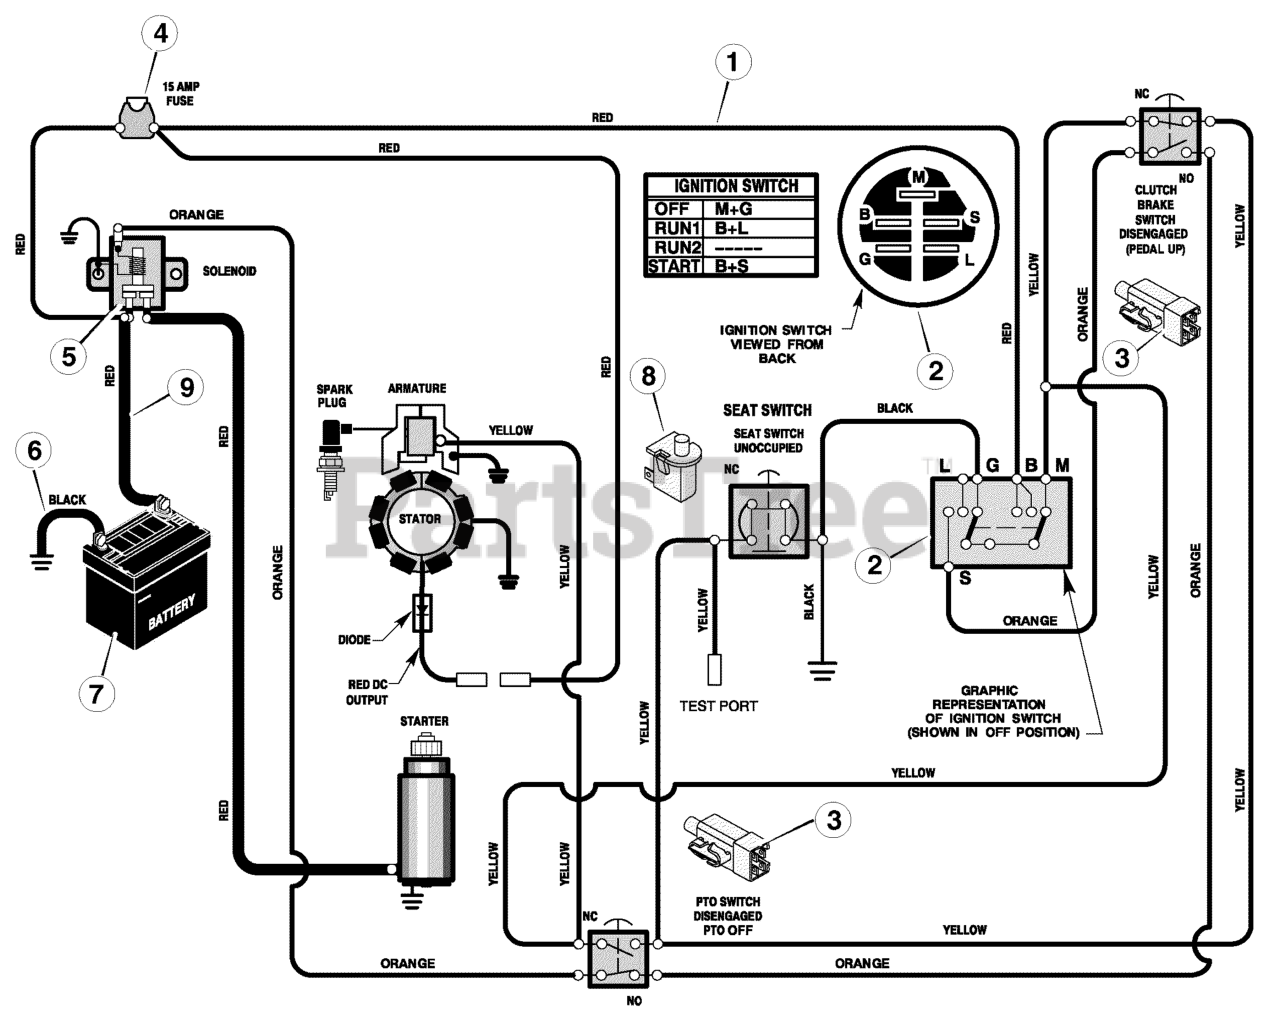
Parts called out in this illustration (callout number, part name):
1	Harness, Chassis Wire
2	Switch, Ignition
2	Key, Ignition
3	Switch, Limit
4	Fuse
4	Holder, Fuse
5	Solenoid
5	Screw, Mounting
5	Locknut
6	Cable, Battery Ground
6	Screw, Ground Cable
7	Battery
7	Bolt, Carriage
7	Wingnut
8	Switch, Seat Sensor
8	Bolt, Carriage
8	Wingnut
9	Cable, Red Batery
9	BOOT, Battery Terminal, Positive
